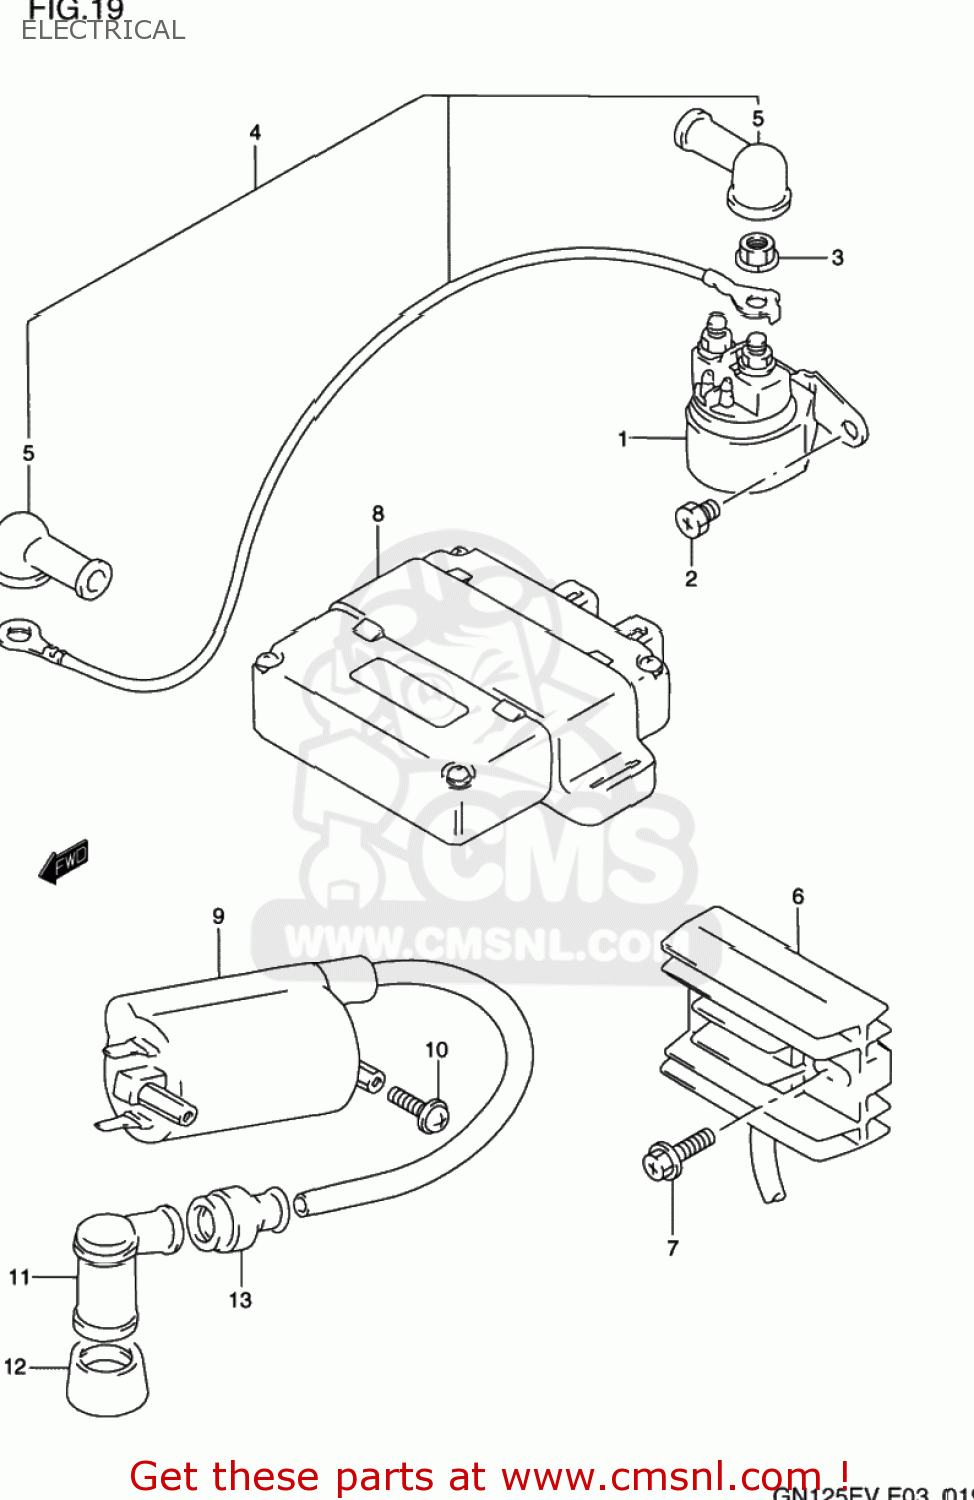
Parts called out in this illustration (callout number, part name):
1	RELAY ASSY,STARTING MOTOR
2	SCREW(6X10)
3	NUT
4	WIRE,STARTER MOTOR
5	CAP,TERMINAL
6	RECTIFIER ASSY
7	SCREW
8	IGNITOR UNIT
9	COIL ASSY,IGNITION
10	SCREW
11	CAP ASSY,SPARK PLUG
12	SEAL,SPARK PLUG CAP
13	SEAL,HIGH TENSION CORD
